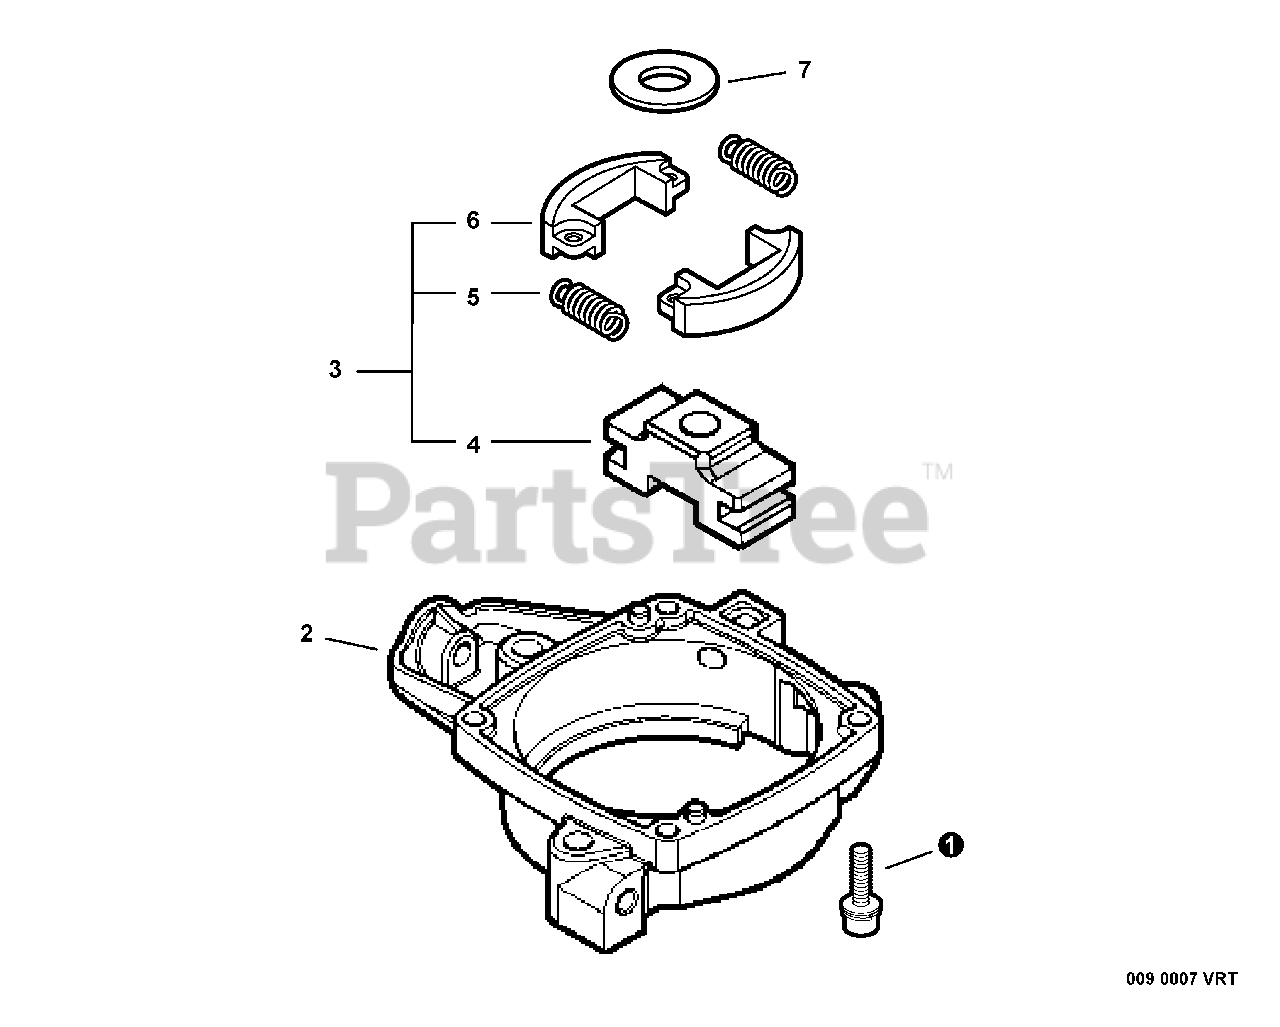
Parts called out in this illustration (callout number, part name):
1	SCREW - 4X16
2	CASE, CLUTCH
3	CLUTCH ASSY
4	HUB, CLUTCH
5	SPRING, CLUTCH
6	SHOE, CLUTCH
7	WASHER - 8
